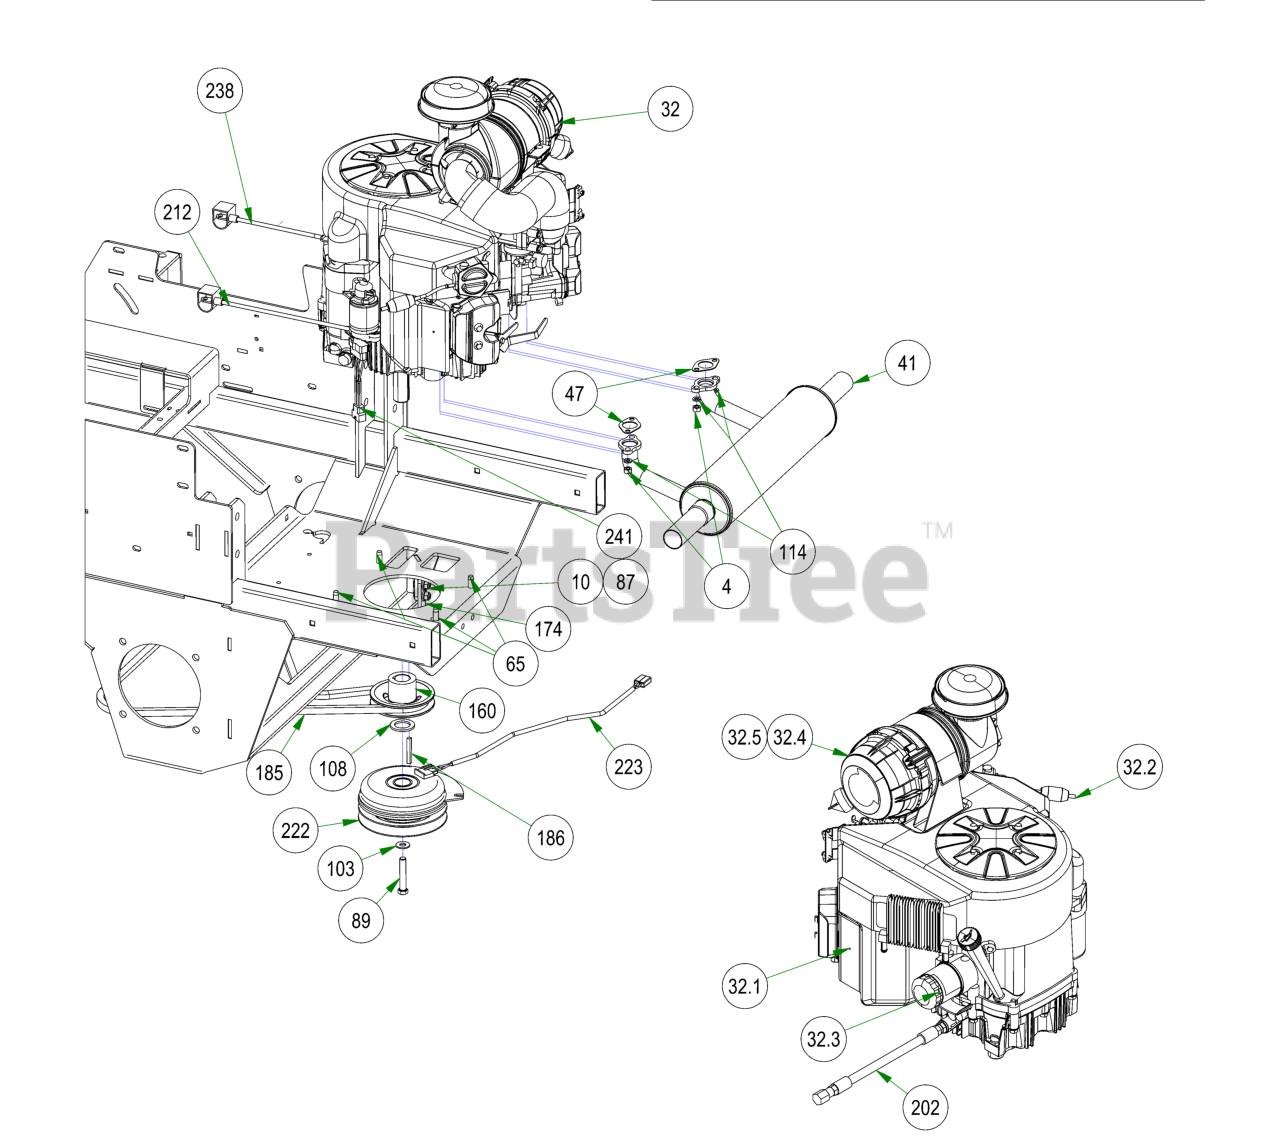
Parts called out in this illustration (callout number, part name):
4	M8-1.25 DIN 934 HEX NUT (CL.8) ZINC
10	3/8-16 NYLON INSERT FLANGE LOCKNUT (GR.F) ZINC
32	Kawasaki FX850 Engine
32.1	Spark Plug - Kawasaki
32.2	Universal Inline Fuel Filter
32.3	Oil Filter
32.4	Canister Air Filter- Outer
32.5	Canister Air Filter- Inner
41	2019 Rebel/Rogue Kawasaki 850 Muffler
47	Exhaust Gasket
65	3/8-16 X 1-1/8HEX WASHER UNSLOT SERRATED
87	3/8-16 X 1 CARRIAGE BOLT (GR.5) ZINC
89	7/16-20 X 2-1/2 HEX Bolt GR 8 W/ Patch
103	3/8 FLAT WASHER USS (1" OD) ZINC
108	1.140 ID X 1.750 OD X .132 THICK FLAT WASHER PLAIN
114	5/16 SPLIT LOCKWASHER ZINC
160	4 3/4 Motor Pulley
174	Rebel Clutch Tab
185	2019 Rebel Pump Belt
186	1/4 X 2 SQ MACHINERY KEY 1018 STL PLAIN
202	Kawasaki Oil Drain
212	14" Red Battery Cable-Base Outlaw
222	Clutch Assembly
223	Clutch Pigtail
224	2023 Rebel Frame - Painted
238	Starter Cable
241	2019 Harness Adaptor-Gen2 FX-ALL
